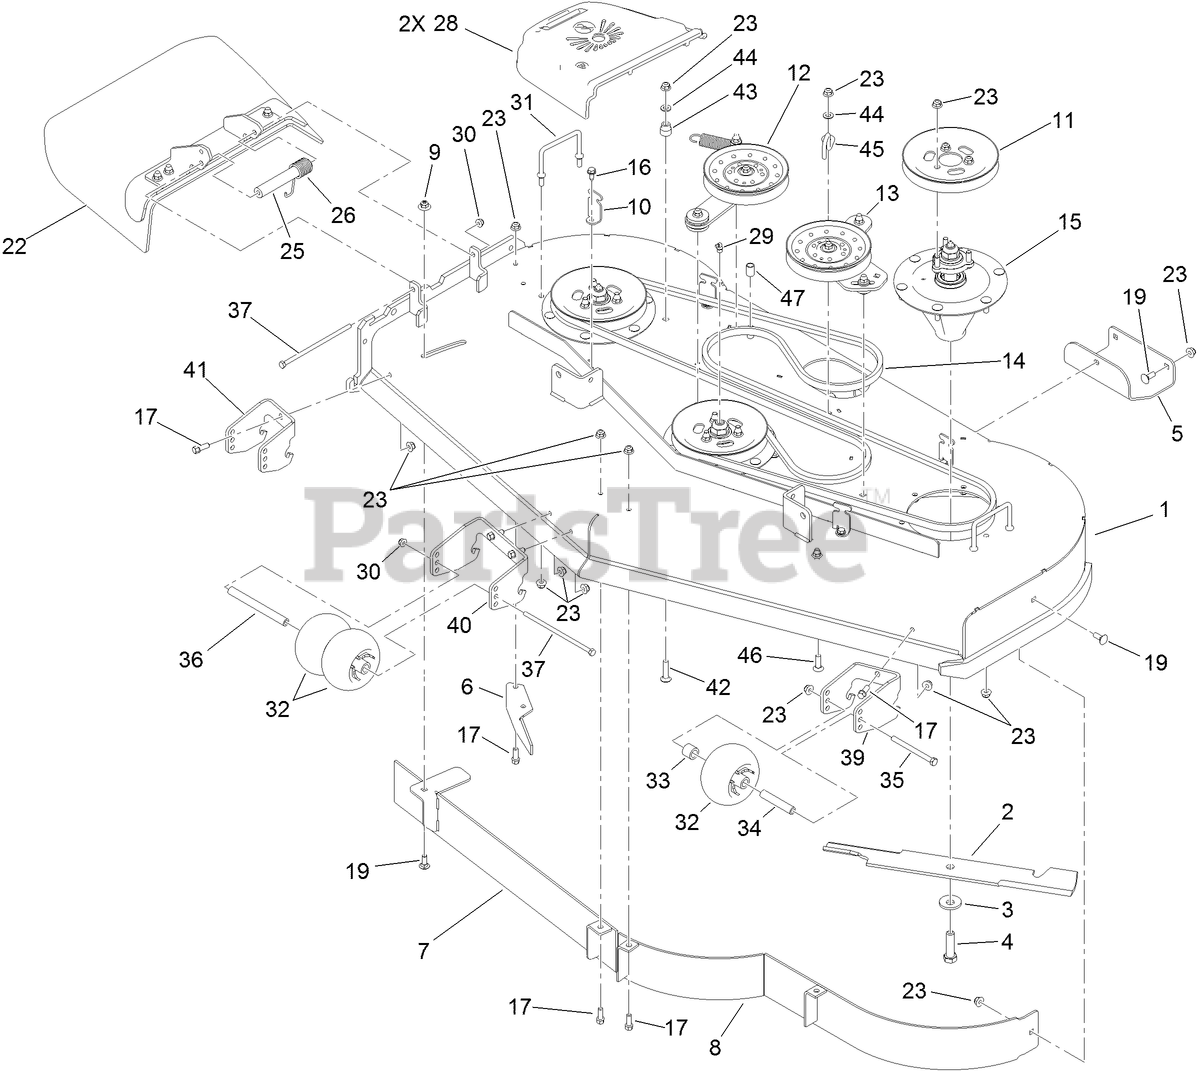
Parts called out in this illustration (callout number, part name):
1	DECK ASM
2	BLADE-HI FLOW
3	Washer-Blade Bolt, Heavy
4	SCREW-BLADE
6	BAFFLE-DISCHARGE
7	BAFFLE ASM
8	BAFFLE ASM
9	NUT-FLANGE, NI
10	BRACKET-COVER
11	PULLEY
12	RH IDLER ARM ASM
13	LH IDLER ARM ASM
14	BELT-V
15	SPINDLE ASM
16	SCREW-HWHTF
17	SCREW-HWH
19	BOLT-CARR
22	DEFLECTOR ASM
23	NUT-HF, NI
25	SPACER
26	SPRING-TORSION
28	COVER-BELT
29	FITTING-GREASE
30	NUT-HF, NI
31	WIREFORM-COVER
32	ROLLER-SCALP, ANTI
33	TUBE-SPACER
34	TUBE-SPANNER
35	SCREW-HH
36	SPACER-WHEEL
37	SCREW-HH
39	BRACKET-WHEEL, LH
40	BRACKET-WHEEL, CENTER
41	BRACKET-WHEEL, RH
42	SCREW-CARR
43	BUSHING-IDLER
44	WASHER-FLAT
45	GUIDE-BELT
46	SCREW-CARR
47	Bumper-Idler
